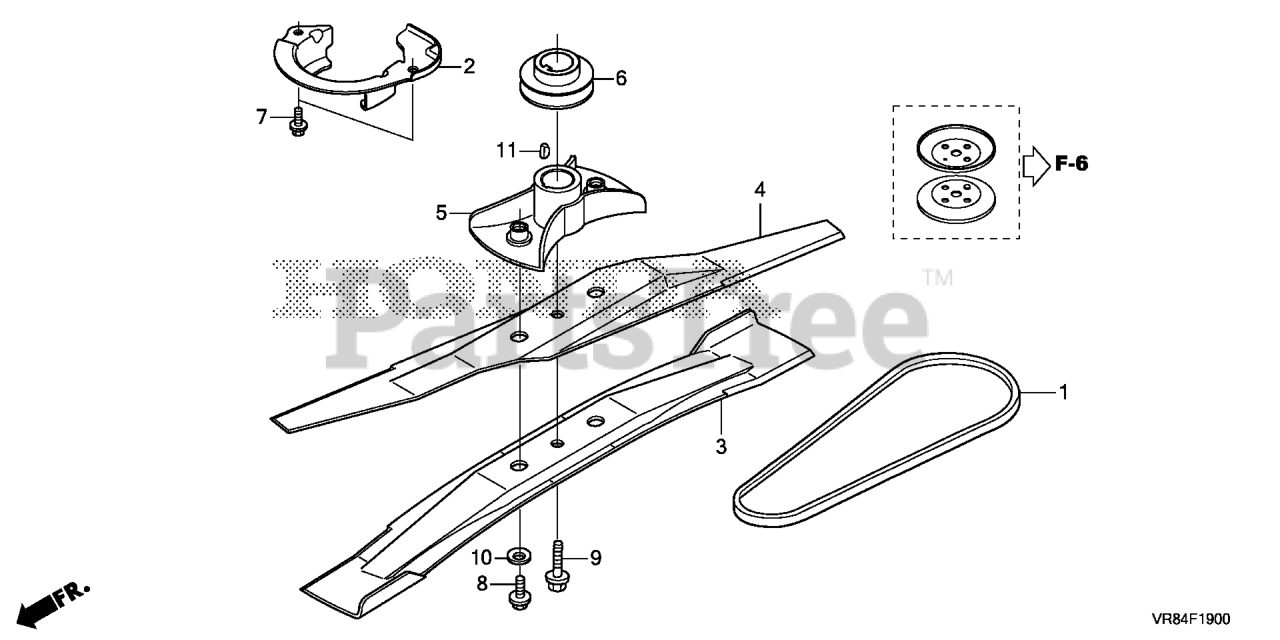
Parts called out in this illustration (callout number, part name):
1	V-BELT (3L-39.2)
2	GUIDE, ENGINE BELT
3	BLADE, ROTARY
4	BLADE, ROTARY (UPPER)
5	HOLDER, BLADE
6	PULLEY, DRIVE
7	BOLT, FLANGE (6X14)
8	BOLT, HEX. (10X25)
9	BOLT, FLANGE (3/8-24X1")
10	WASHER, SPRING (10MM)
11	KEY, WOODRUFF (3/16X5/8)
